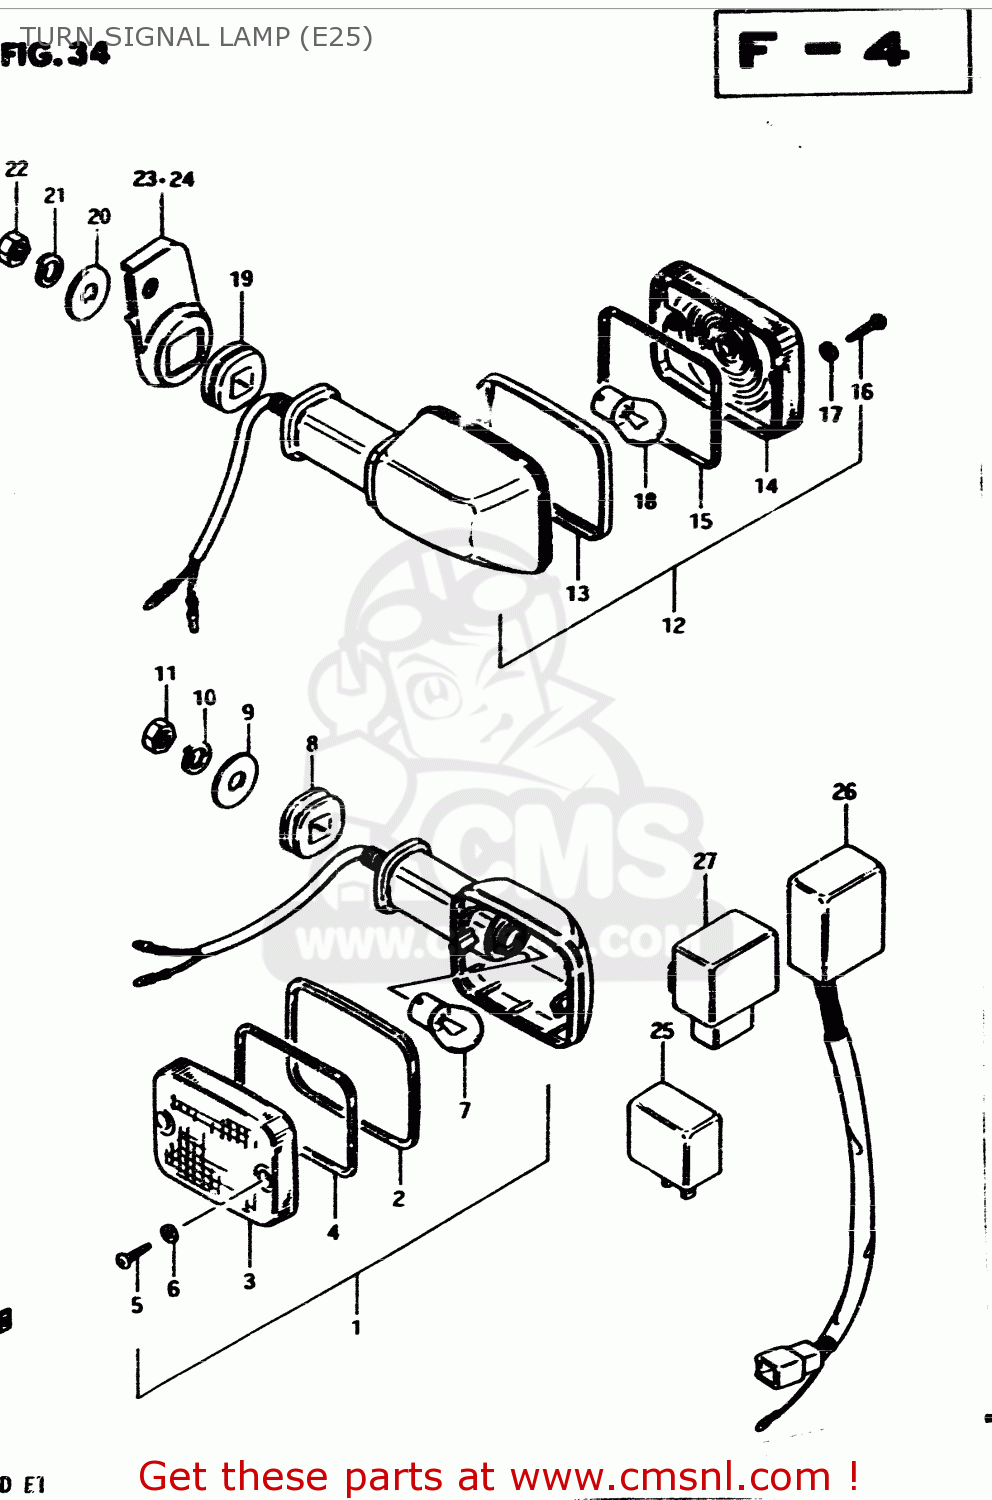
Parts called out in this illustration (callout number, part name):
1	LAMP ASSY,FR T
2	RIM
3	LENS
4	GASKET (NAS)
5	SCREW
6	GASKET (NAS)
7	BULB(12V21W)
8	CUSHION
9	WASHER (10.5X30X2.3)
10	LOCK WASHER
11	NUT
12	LAMP ASSY,RR T
13	RIM
14	LENS
15	GASKET (NAS)
16	SCREW
17	GASKET (NAS)
18	BULB(12V21W)
19	CUSHION
20	WASHER (10.5X30X2.3)
21	LOCK WASHER
22	NUT
23	BRACKET,REAR TURN SIGNAL
24	BRACKET,REAR TURN SIGNAL
25	RELAY ASSY,TURNSIGNAL
26	UNIT,TURN SIGNAL CONTROL
27	UNIT,TURN SIGNAL CONTROL
